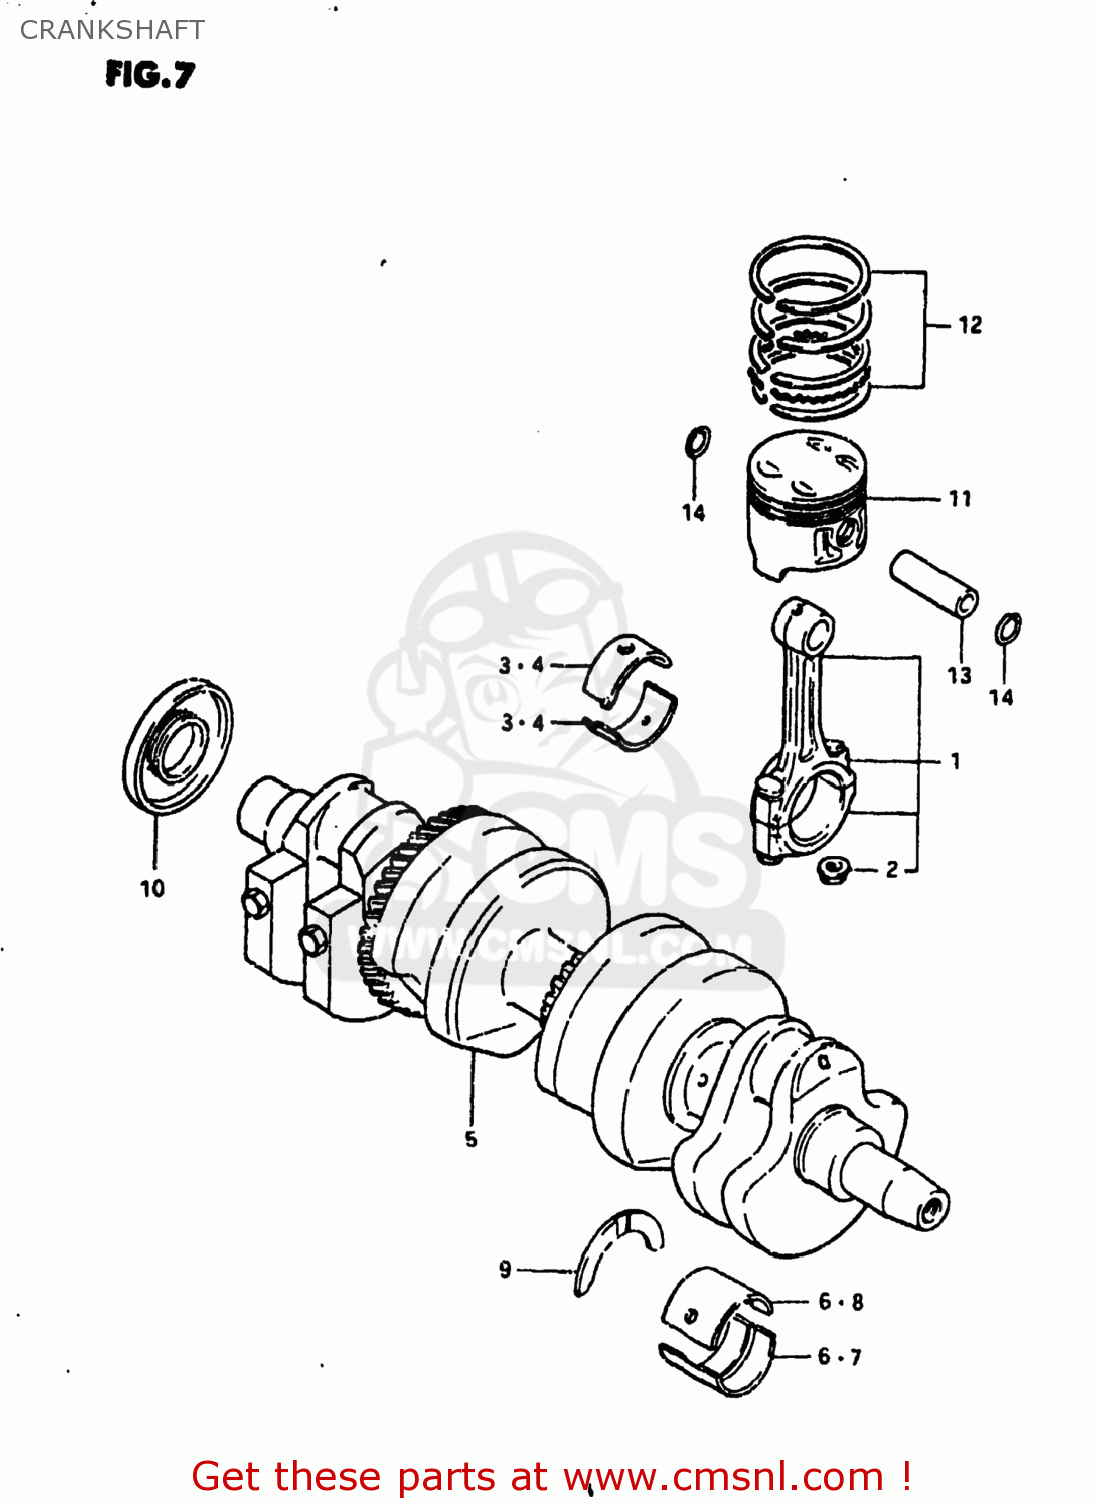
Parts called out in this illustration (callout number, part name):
1	CONNECTING ROD ASSEMBLY
2	NUT
3	BEARING,CRANK PIN
4	BEARING,CRANK PIN
5	CRANKSHAFT
6	METAL CRANKSHAFT
7	METAL CRANKSHAFT
8	METAL CRANKSHAFT
9	PLATE,CRANK THRUST
10	OIL SEAL
11	PISTON
12	RING SET,PISTON
13	PIN,PISTON (18MM)
14	CIRCLIP
